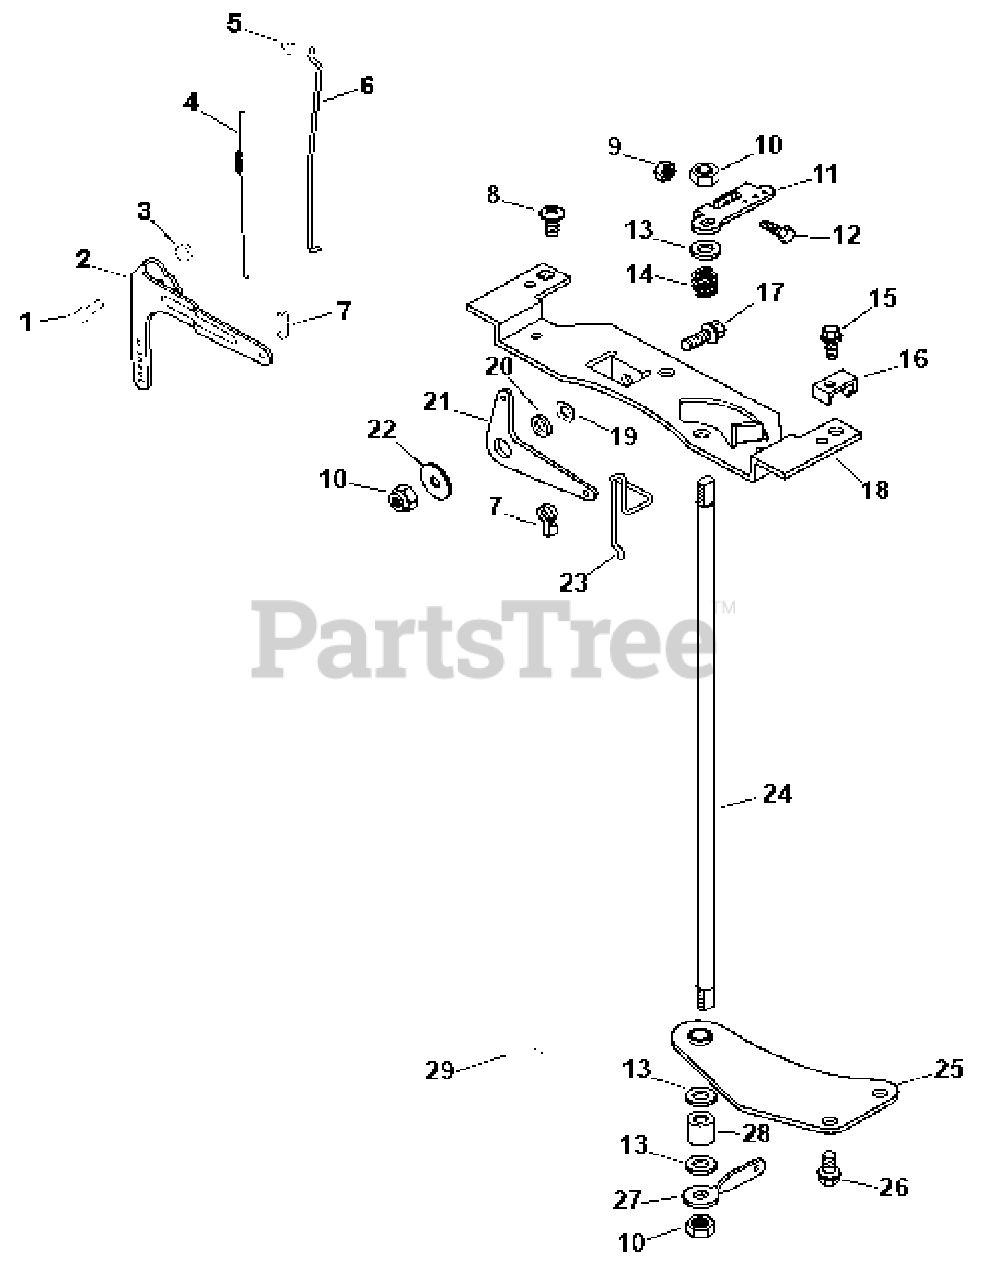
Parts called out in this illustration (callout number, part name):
1	Round Head Sq.Neck Bolt
2	Governor Lever
4	Linkage Spring
5	Linkage Retainig Bushing
6	Throttle Linkage
7	Linkage Retainig Bushing
11	Throttle Control Lever
14	Throttle Shaft Spring
15	Screw
16	Cable Clamp
17	Hex Flange Screw
18	Control Bracket
23	Choke Linkage
24	Throttle Shaft
25	Throttle Shaft Bracket
27	Throttle Control Lever
29	Governor Spring
